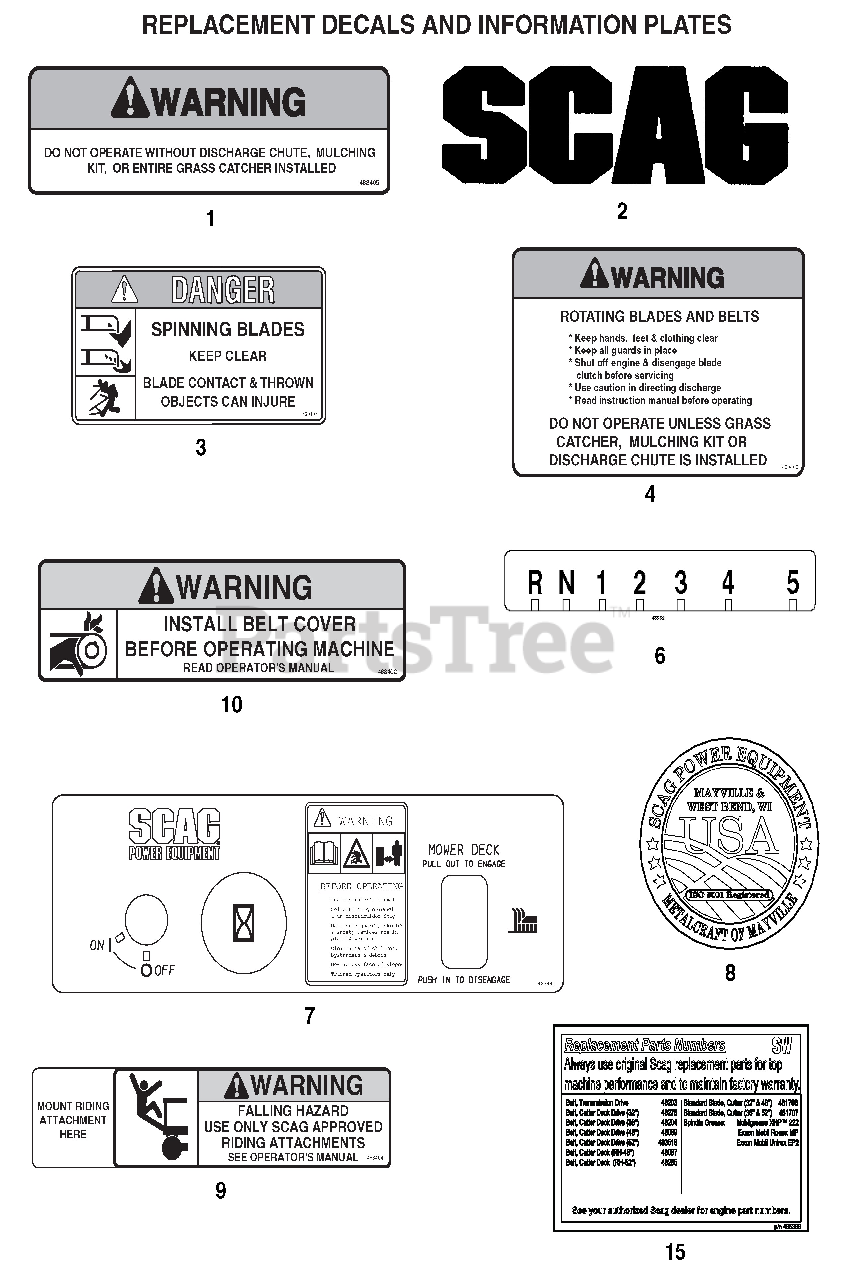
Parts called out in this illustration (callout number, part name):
1	Decal, Discharge Chute
2	Decal, Scag Logo
3	Decal, Danger-Spinning Blades
4	Decal, Warning-Rotating Blades
6	Decal, Shift Index
7	Decal, Instrument Panel - Rear
8	Decal, Metalcraft - USA
9	Decal, Sulky Attachment
10	Decal, Belt Cover
15	Decal, SW Replacement Parts
